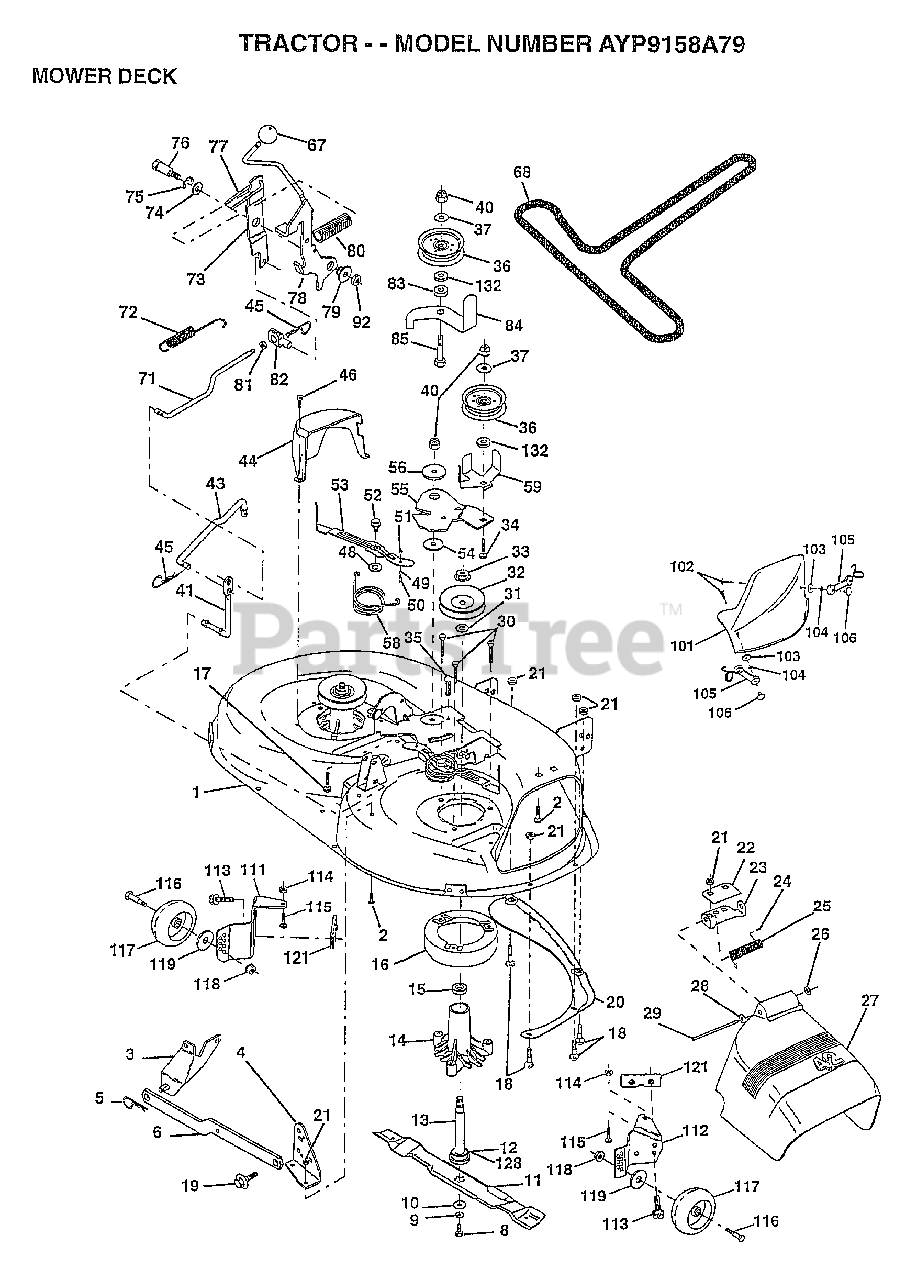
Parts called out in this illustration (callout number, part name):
1	DECK.WELD.42.
2	BOLT
3	BRKT ASM SWAY BAR
4	BRKT DECK SW BAR
8	BLADE BOLT
10	WASHER.HARD.BLADE
11	"BLADE.42"" MULCHER"
12	BEARING.BALL
12	BRACKET.GWHL.RH.
13	SCREW
14	HSG ASM MANDREL
15	BEARING
16	STRIPPER RND MWR
17	BOLT RDHD 3/8-16
18	BOLT
19	BOLT SHD 5/16-18
22	STIFFENER BRKT
23	DEFLECTOR BRKT
24	CAP-SLEEVE LT
25	SPRING TORSION
26	NUT PUSH M
27	DEFLECTOR.SHIELD
28	WASHER
29	HINGE ROD
31	WASHER
32	PULLEY.MANDREL.42
34	BOLT
35	XMAS TREE FASTNER
36	FLAT IDLER PULLEY
37	WASHER
41	PIVOT ROD
43	ROD CLUTCH W/NIBS
44	GUARD MAND LH BLK
45	RETAINER M
46	SCREW.1/4-20X5/8
48	HARD SMALL WASHER
49	ROLLER ASM-CAM
50	SHOULDER BOLT
51	LOCKNUT
52	BOLT.SHLD.5/16-18
54	HARDENED WASHER
55	ARM-IDLER
56	SPACER RETAINER
58	SPRING TORSN BRAK
59	GUARD IDLER TUV
67	KNOB T(3/8 HOLE)
68	BELT.V.T-PATH
71	ROD CLUTCH 38/42
72	RETURN SPRING
73	CLUTCH ARM SECOND
74	WASHER
75	RING
76	SHOULDER BOLT
77	SPRING KEEPER
78	LEVER ASM-CLUTCH
79	BUSHING
80	SPRING.CLUTCH.MWR
81	NUT
82	TRUNION ADJ
83	WASHER
84	"KEEPER-BELT,FIXED"
85	BOLT RDHD 3/8-16
92	NUT
101	"COVER.MULCH.42"""
102	SCREW
103	WASHER #10
104	LOCKWASHER
106	WELDNUT
111	BRACKET.GWHL.LH.
116	BOLT.SHOULDER
117	WHEEL GAGE DONUT
118	LOCKNUT
119	WASHER
121	BRACKET.EXTRD.GWL
128	WASHER.FELT.
132	WASHER GT
